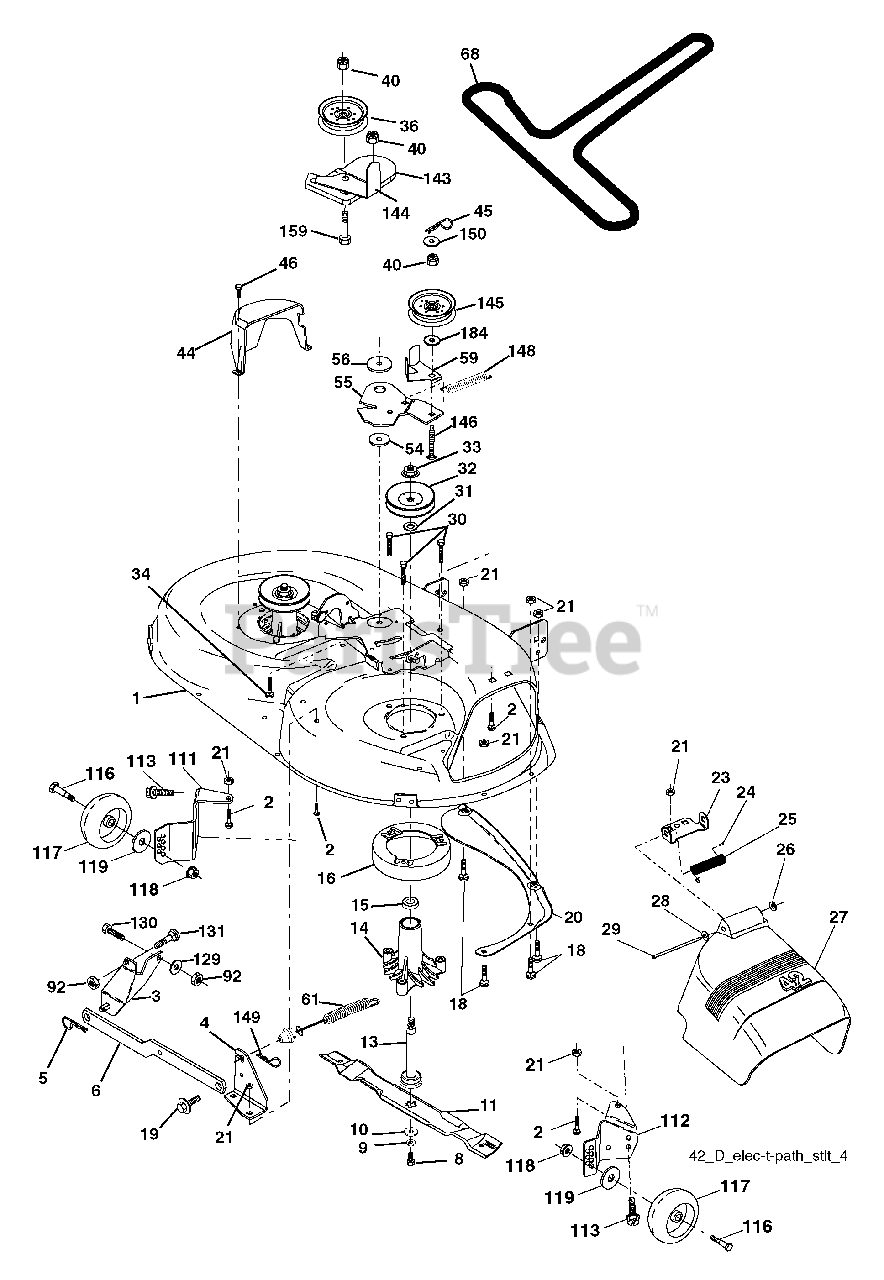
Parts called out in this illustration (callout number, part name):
1	Mower Deck Assembly, 42"
2	Bolt
3	Bracket Asm Fr. Sway Bar 3/42
4	Bracket Asm Deck 42" Sway Bar
5	Retainer Spring
6	Bar Sway Deck
8	Bolt 3/8-24 x 1.25 Gr. 8 patched
9	Washer, Lock
10	Washer, Hardened
11	Blade Mower 42" Hi-Lift
11	Blade, Mulching 42" Std
11	Blade Mulching 42" Premium
13	Shaft Assembly, Mandrel, Vented
14	Housing, Mandrel, Vented
15	Bearing, Ball, Mandrel
16	Stripper, Mandrel Deck
18	Bolt, Carriage 5/16-18 x 5/8
19	Bolt, Shoulder
20	Baffle, Vortex
21	Nut
23	Bracket, Deflector Mower 42"
24	Cap, Sleeve 80 x 112 Blk Mower
25	Spring, Torsion, Deflector 2 52
26	Nut, Push Phos & Oil
27	Shield, Deflector 42" Blk
28	Washer 11/32 x 5/8 x 16 Ga.
29	Rod, Hinge 42" 6 75 W/G
30	Screw Thdrol
31	Washer, Spacer Mower Vented
32	Pulley, Mandrel
33	Nut, Toplock
34	Bolt Carr SH 3/8-16 x 1-1/2 Gr.5
36	Pulley, Idler, Flat
40	Nut Lock 3/8-16
44	Guard, Mandrel, LH
45	Retainer
46	Screw, Thdrol 1/4-20 x 5/8 T
54	Washer, Hardened
55	Arm, Idler
56	Spacer, Retainer
59	Guard TUV Idler
61	Spring Ext Elect. Clutch
68	V-Belt, 42" Mower
92	Nut Lock Hex w/Ins 3/8-16 unc
111	Bracket Whl Ga. LH
112	Bracket Whl Ga. RH
113	Screw 5/16-18
116	Bolt, Shoulder
117	Wheel, Gauge
118	Nut Centerlock 3/8-16
119	Washer 3/8 x 7/8 x 14 Ga.
129	Washer 13/32 x 13/16 x 12 Ga.
130	Bolt Fin HEx 3/8-16 unc x 1 Gr. 5
131	Bolt RDHD SQNK 3/8-16 unc x 1
143	Bracket Arm Idler 42"
144	Keeper Belt 42" Clutch Cable
145	Pulley Idler Flat
146	Bolt Carriage Idler
148	Spring Return Idler
149	Retainer Spring Yellow
150	Washer 9/32 x 3/4 x 10 Ga.
159	Bolt Rdhd Sqn 3/8-16 unc x 1-3/4
184	Washer 13/32 x 7/8 x 10 Ga.
